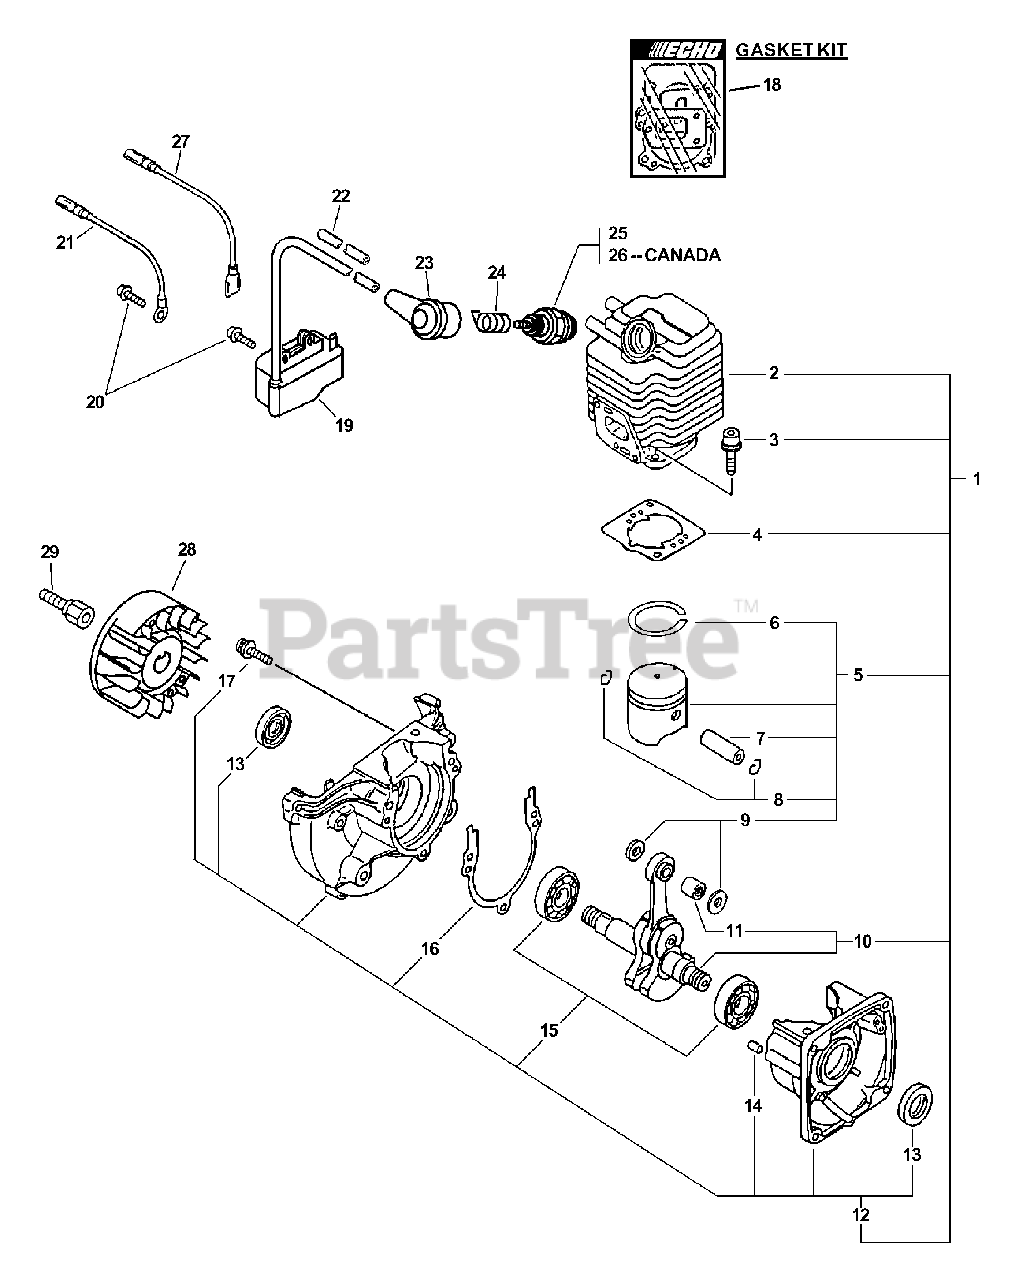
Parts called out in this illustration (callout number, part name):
1	SHORT BLOCK
2	CYLINDER
3	BOLT 5×22
4	GASKET, CYLINDER
5	PISTON KIT
6	RING, PISTON
7	PIN, PISTON 8
8	RING, SNAP
9	WASHER, THRUST
10	CRANKSHAFT ASSY
11	BEARING, NEEDLE
12	CRANKCASE KIT
13	SEAL, OIL 12
14	PIN, LOCATING 4
15	BEARING, BALL - 6201 C3
16	GASKET, CRANKCASE
17	BOLT 5×28
18	GASKET KIT
19	COIL, IGNITION
20	BOLT 4×20
21	LEAD - GROUND
22	TUBE, INSULATOR
23	CAP, SPARK PLUG
24	TERMINAL, SPARK PLUG
25	SPARK PLUG - BPM8Y
26	SPARK PLUG - BPMR8Y
27	LEAD - IGNITION
28	FLYWHEEL
29	HUB, FAN
